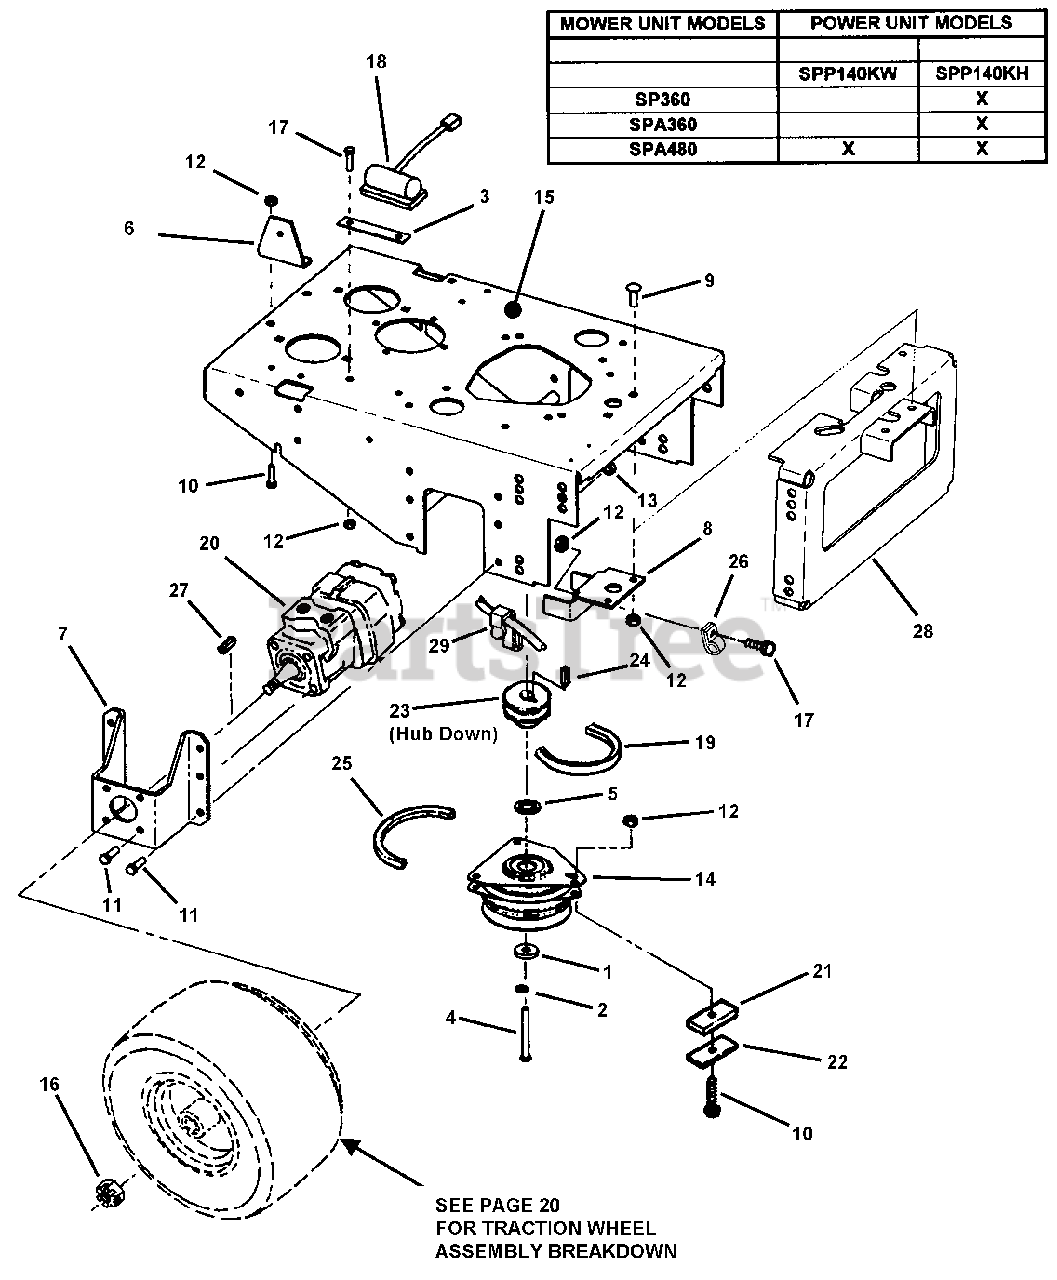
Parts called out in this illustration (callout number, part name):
1	SPACER, Clutch
2	WASHER, 7/16" Split
3	BRACKET, Capacitor
4	SCREW, M10-1.5 x .55 Hex Head Cap
5	BUSHING, 1-1/2" O.D. x 1" I.D.
6	BRACKET, Pivot
7	BRACKET, Wheel
8	BRACKET, Clutch
9	BOLT, 5/16-18 x 1", Round Head Short Square Neck, Grade 5
10	BOLT, 5/16-18 X 1-1/4 GD5 YZ
11	BOLT, 3/8-16 X 1" GD5 CZ
12	NUT, 5/16-18 Top Lock, Grade B
13	NUT, 3/8-16, HEX TOP LOCK
14	CLUTCH, Electric
15	DECK, Rear (Weldment)
16	NUT, Pack
17	BOLT, 5/16-18 X 3/4 GD5
18	CAPACITOR, Kawasaki Engine
19	V-BELT, HA4950 Engine/Hydro (49.50" Effective Length)
20	MOTOR, Wheel
21	BUMPER, Electric Clutch
22	SUPPORT, Electric Clutch Bumper
23	PULLEY, Engine/Hydro 4"
24	KEY, 1/4" Square X 1"
25	BELT, Engine/Deck (36")
26	CLIP, Harness
27	KEY, 3/16" Square x 3/4"
28	BRACE, Engine Frame
29	CLIP, Harness
